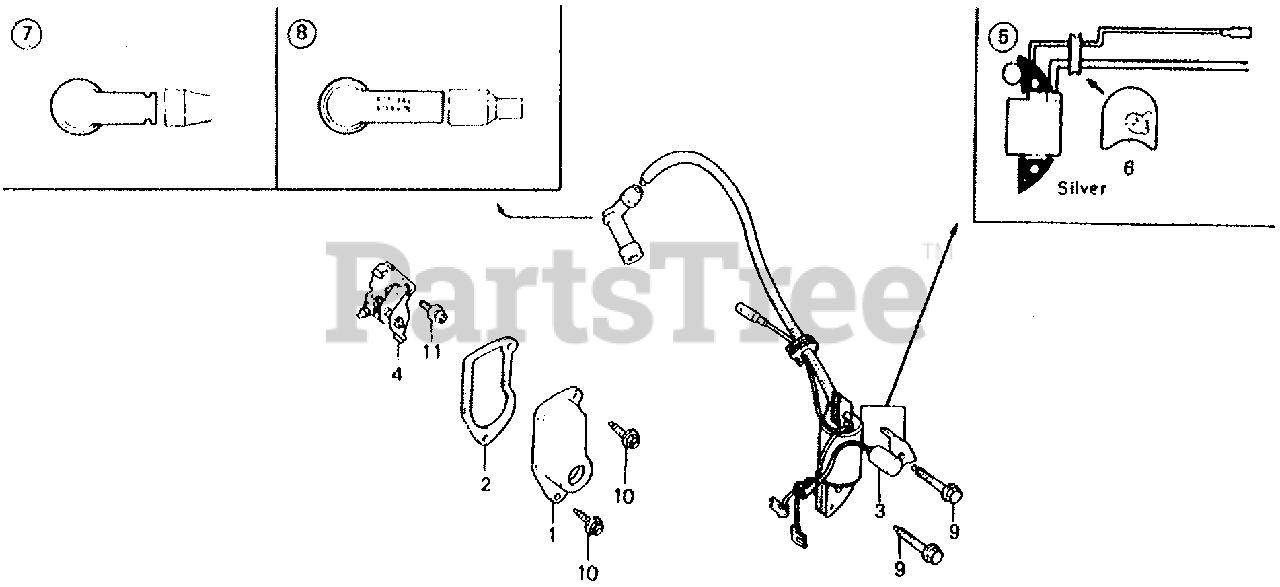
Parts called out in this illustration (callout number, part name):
1	COVER, POINTS
2	GASKET, POINT COVER
3	CONDENSER
4	POINTS ASSY.
5	COIL ASSY., IGNITION
6	GROMMET, WIRE
7	TERMINAL ASSY., IGNITION
9	BOLT, FLANGE (6X32)
10	BOLT, FLANGE (5X10)
11	SCREW-WASHER (5X12)
